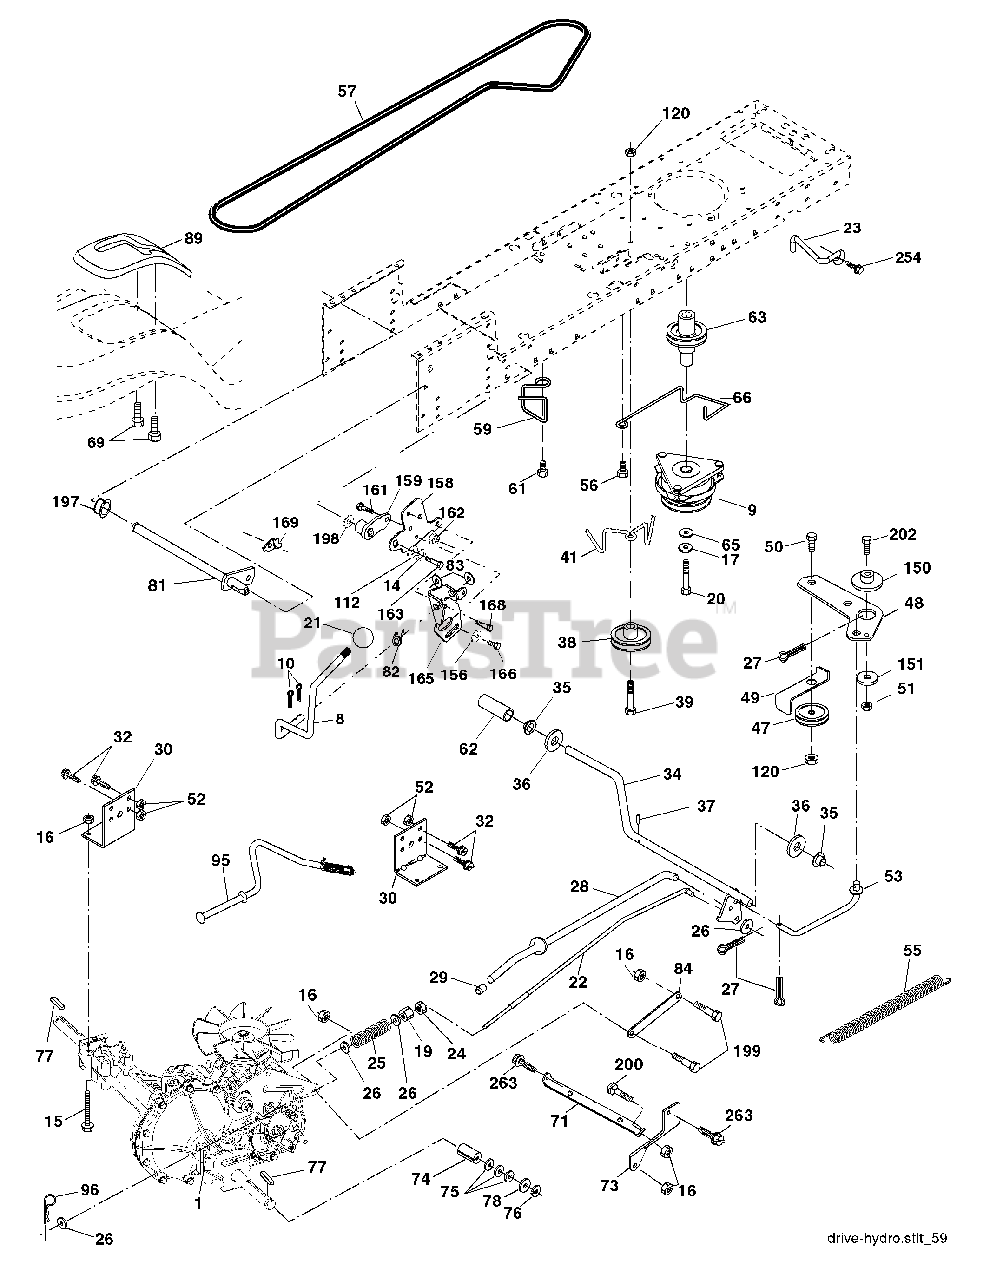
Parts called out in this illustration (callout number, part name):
8	Rod Shift Fender
9	Clutch Electric
10	Pin Cotter 1/8 x 1 CAD
14	Washer Lock Hvy Helical
15	Bolt Hex Flghd 5/16-18 Gr. 5
16	Nut Lock Hex W/Ins. 5/16-18 unc
17	Washer 1-1/2 OD x 15/32 ID x .250
19	Nut Lock Hex W/Wsh 3/8-16 unc
20	Bolt, Hex 7/16-20 x Gr. 5-1.5
22	Rod, Brake Hydro
23	Bracket Asm. Anti-Rot
24	Locknut
25	Spring, Brake Rod
26	Washer
27	Pin Cotter 1/8 x 3/4 CAD.
28	Rod, Parking Brake
29	Cap, Parking Brake
30	Bracket, Transaxle
32	Bolt Hex Hd 5/16-18 unc x 3/4
34	Shaft, Foot Pedal Nibbed
35	Bearing, Nylon
37	Pin, Roll
38	Pulley, Idler, Flat Composite
39	Bolt 3/8-16 x 2-3/4 Gr. 5
41	Keeper, Belt Idler Fool-Proof
47	Pulley, Idler, V-Groove
48	Bellcrank Clutch Grnd Drv Stl
49	Retainer, Belt
50	Bolt Carr. SH 3/8-16 x 1-1/2 Gr. 5
52	Nut Crown Lock 5/16-18
53	Link, Clutch
55	Spring, Return, Clutch
56	Screw 3/8-16 x 1-1/4
57	V-Belt, Ground Drive
59	Keeper, Center Span
61	Screw 3/8-16 x .875
62	Cover, Pedal
63	Pulley, Engine
65	Washer
66	Keeper Belt Engine Hydro
69	Screw Hex Wsh Hi-Lo 1/4-1/2
71	Strap Torque Lh Hydro
73	Strap Torque Rh Hydro
74	Spacer, Axle
75	Washer 25/32 x 1-1/4 x 16 Ga.
77	Key, Square
78	Washer 25/32 x 1-5/8 x 16 Ga.
81	Shaft Asm. Cross Hydro
82	Spring Torsion T/A
83	Washer 17/32 x 3/4 x 16 Ga.
84	Link Transaxle
89	Console, Shift
95	Control Asm. Bypass Hydro
96	Retainer Spring 1" Zinc/Cad
112	Washer 9/32 x 3/4 x 10 Ga.
120	Nut Lock 3/8-16
150	Spacer Retainer
151	Washer 13/32 x 2 x 10 Ga.
156	Washer Srrted 5/16 ID x 1.125
158	Bracket Shift Mount
159	Hub Shift
161	Bolt Rdhd Sqnk 1/4-20 x 3/4 Gr. 5
162	Nut Crownlock 1/4-20 unc
163	Bolt Hex Fin 1/4-20 unc x 1 Gr. 5
165	Bracket Pivot Lever
166	Screw 5/16-18 x 5/8
168	Bolt Shoulder 5/16-18 x .561
169	Plate Fastening Lt\
197	Nyliner Snap-In 5/8" ID
198	Washer Nyliner 7/8 ID x .105
199	Bolt Shoulder 5/16-18 unc
200	Bolt Rdhd Sq Neck 5/16-18 unc x 1
202	Bolt 3/8-16 x 1-3/4 Gr. 5
254	Screw 3/8-16 x 1
263	Screw Hexwsh Thdr 3/8-16 x 3/4
